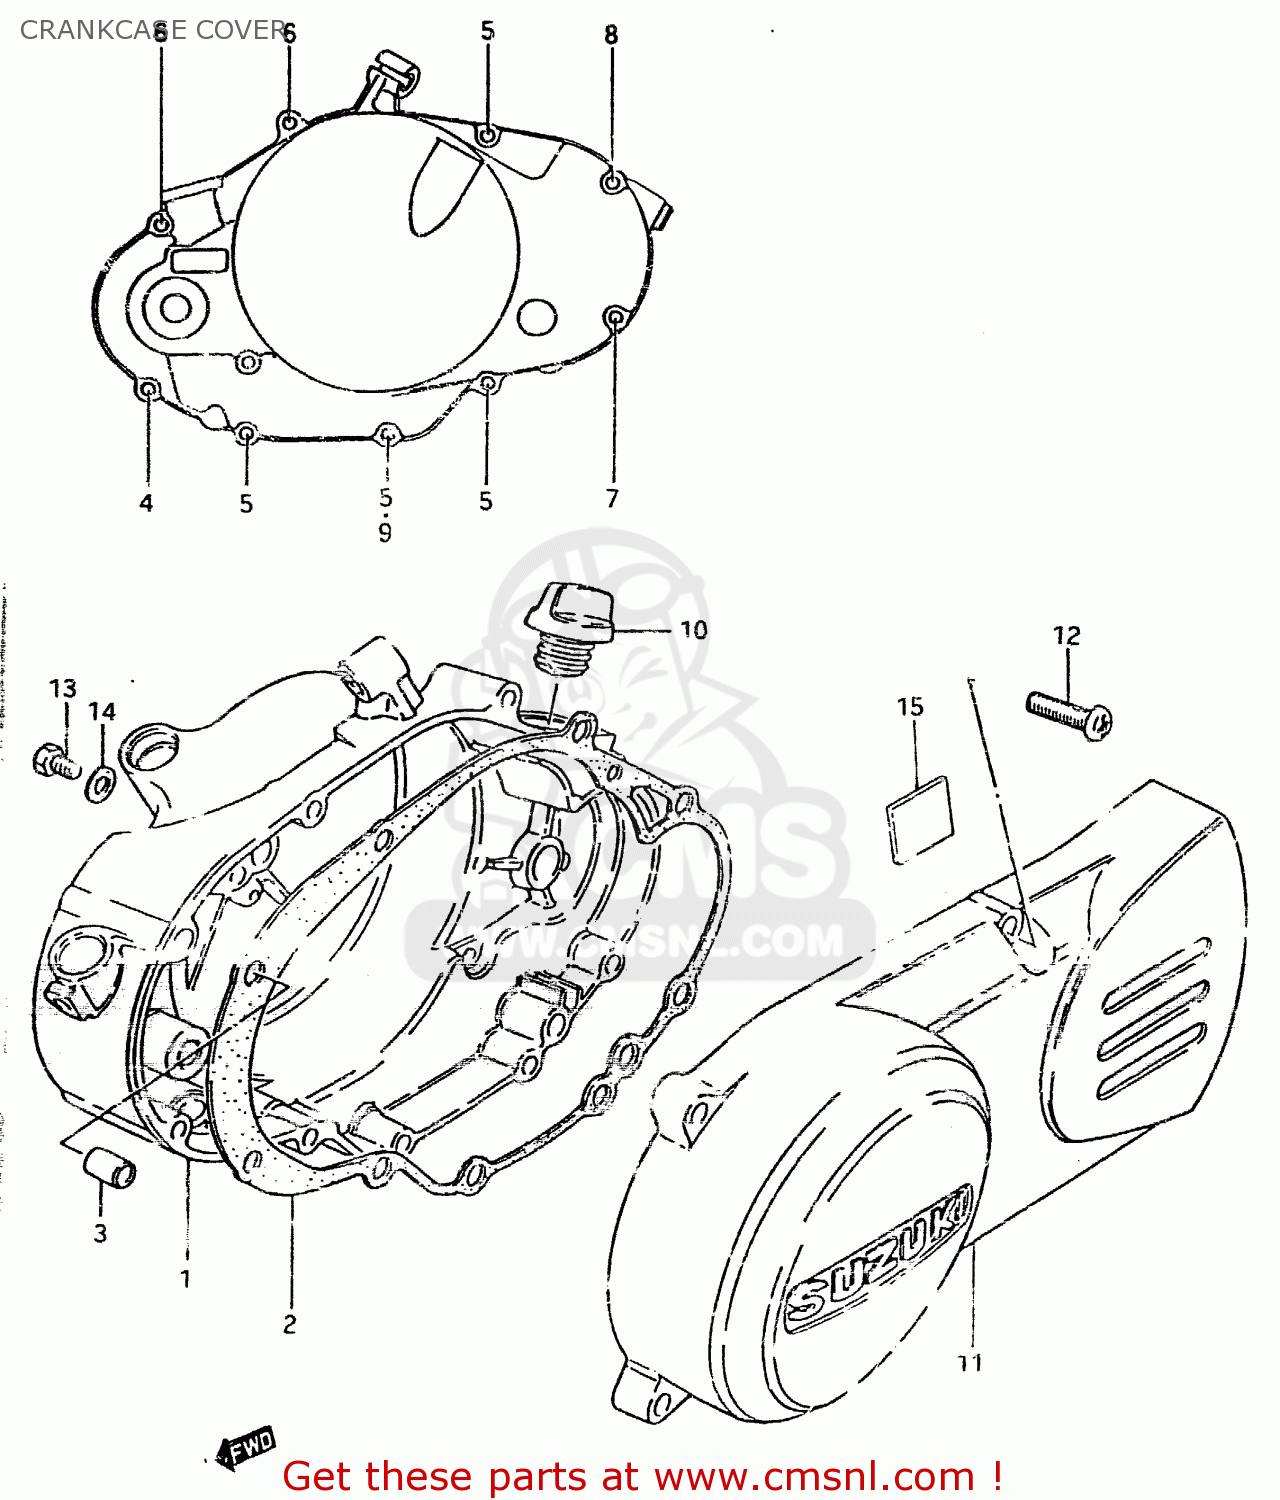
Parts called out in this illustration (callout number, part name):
1	COVER SET,CLUTCH
2	GASKET,CLUTCH COVER (MCA)
3	PIN
4	SCREW
5	SCREW 6X30
6	SCREW
7	SCREW
8	SCREW 6X60
9	GASKET(6.2X11X1).2 (NAS)
10	PLUG
11	COVER,MAGNETO
12	SCREW
13	SCREW
14	GASKET(6.2X11X1) (NAS)
15	DAMPER,MAGNETO COVER
